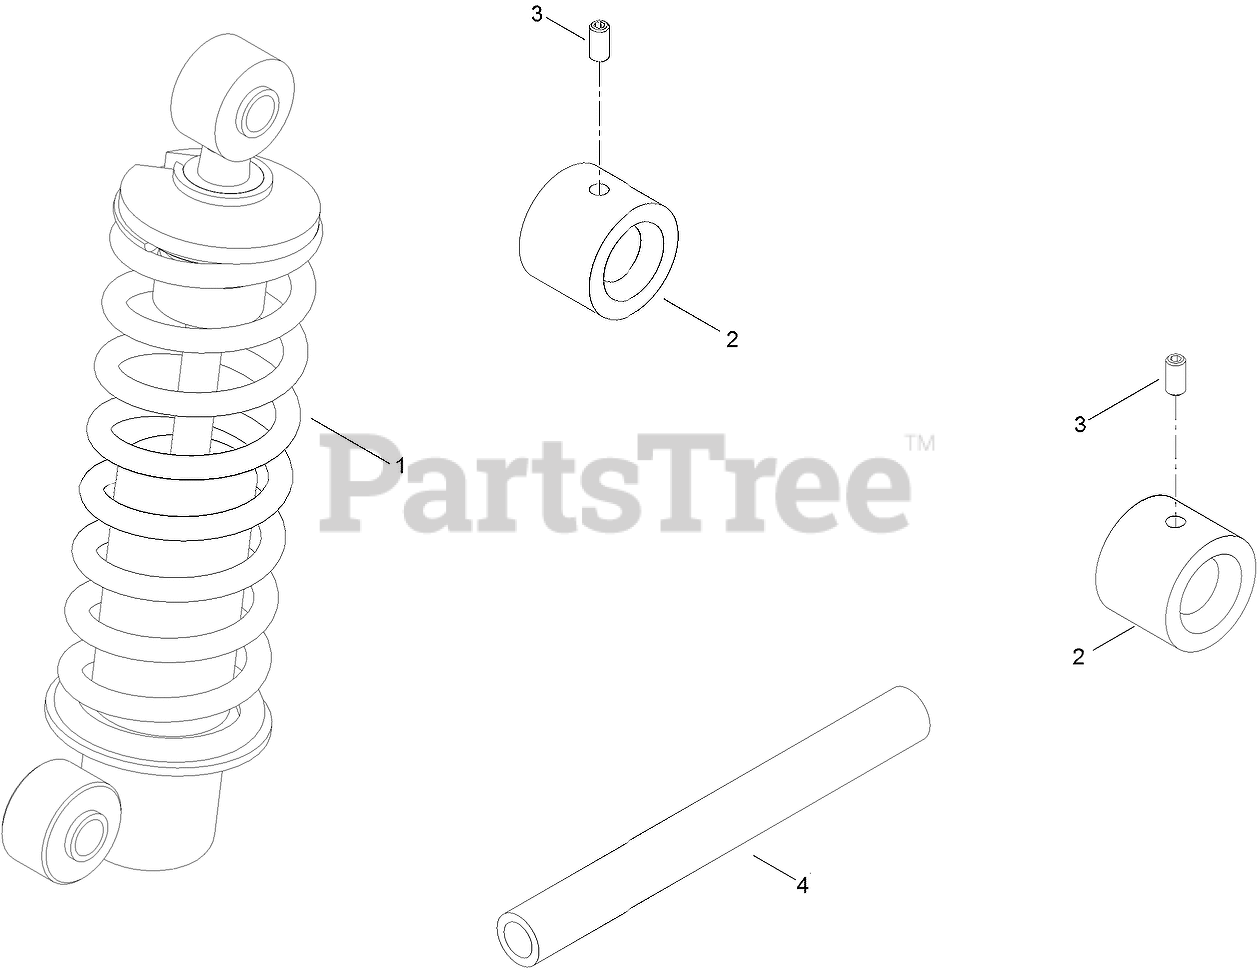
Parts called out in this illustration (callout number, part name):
1	SHOCK/SPRING ASM
2	SPACER - SPRING
3	SCREW-SET, HSH
4	TUBE-SPRING LIFT
